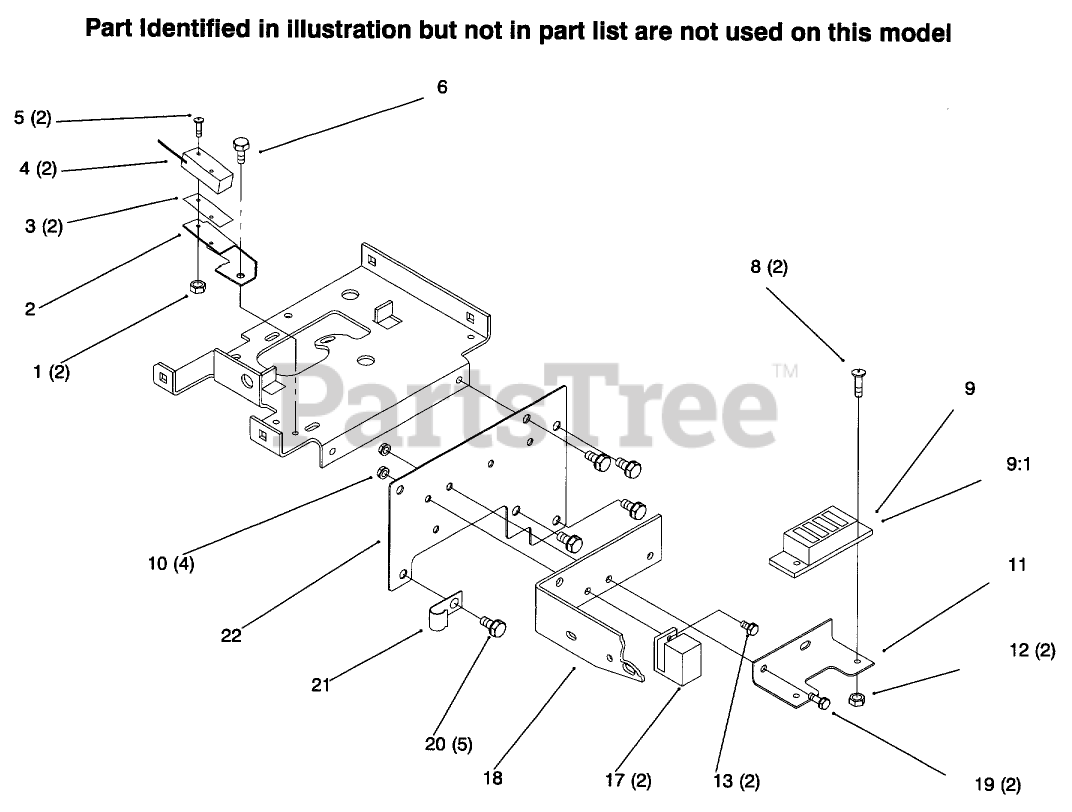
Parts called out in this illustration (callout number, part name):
1	NUT-HEX, NYL INS
3	BARRIER - SWITCH
4	SWITCH
5	SCREW-PHL 4-40X1 1/4
6	SCREW-HWH
8	SCREW-PAN
9	WIRING-HARNESS & DIA
10	NUT-LOCK, NI
11	BRKT-FUS HLDER*B
17	RELAY
18	BRACKET-BELT*B
19	SCREW-HH
21	CLIP
